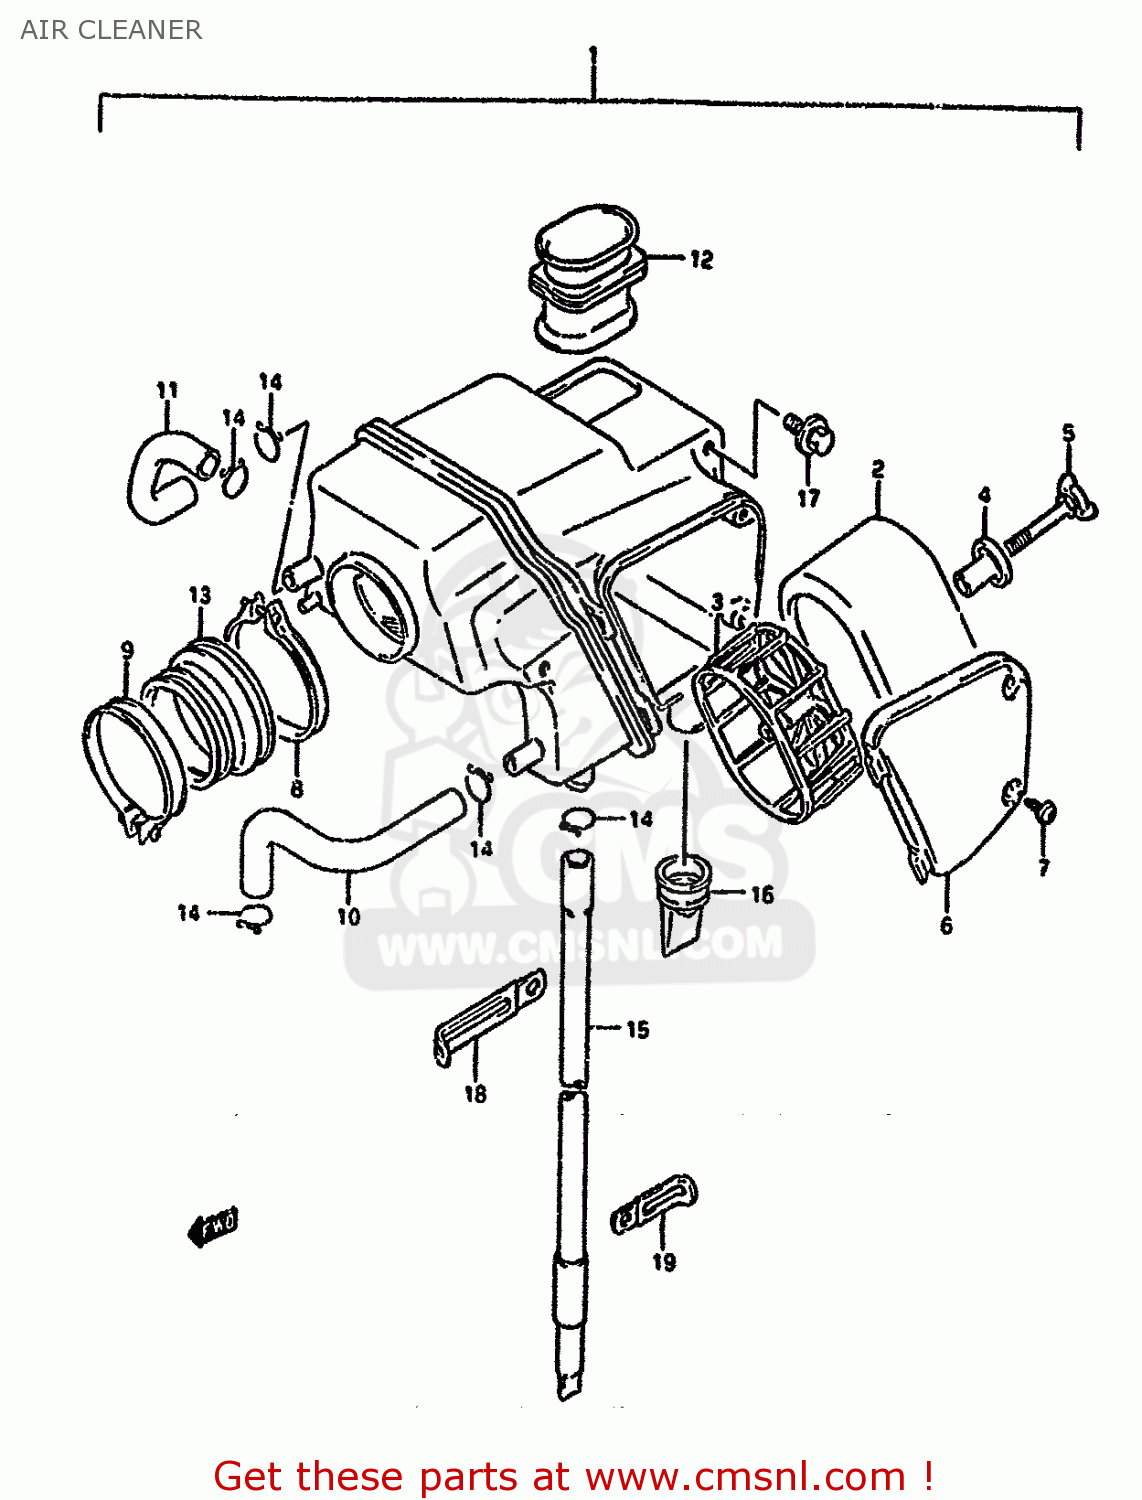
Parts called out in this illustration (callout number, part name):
1	CLEANER ASSY,AIR
2	FILTER
3	HOLDER,FILTER
4	SPACER
5	BOLT,WING
6	CAP,AIR CLEANER
7	SCREW
8	CLAMP
9	CLAMP
10	TUBE,BREATHER
11	TUBE,CONNECTING
12	TUBE,INLET
13	TUBE,OUTLET
14	CLIP
15	DRAIN TUBE
16	CAP,DRAIN
17	BOLT(6X14)
18	CLAMP
19	CLAMP
